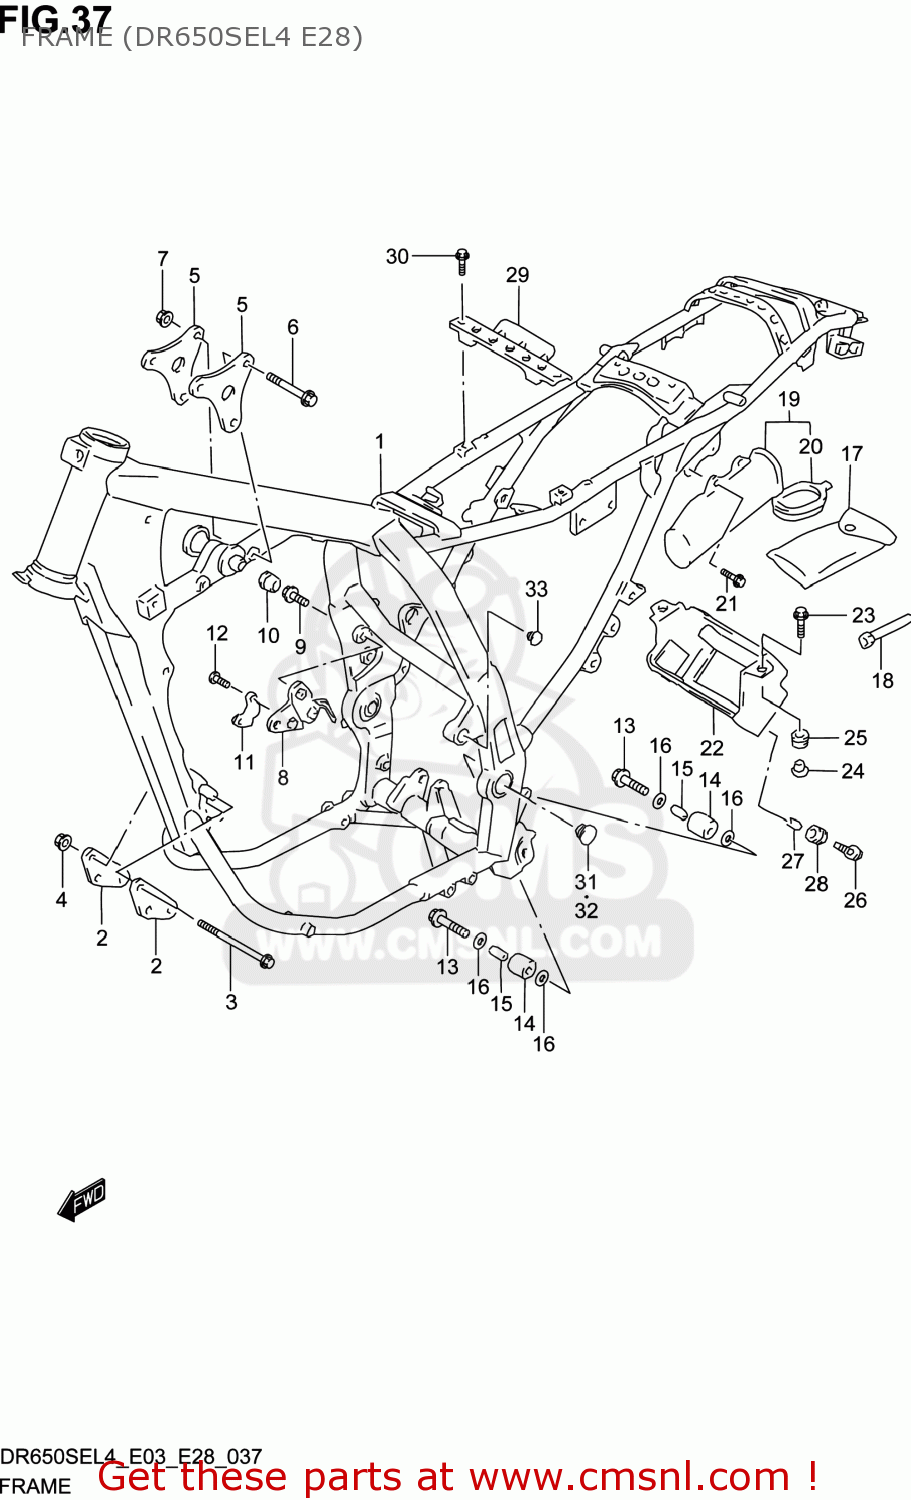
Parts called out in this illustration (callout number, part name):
1	FRAME(GLAY)
2	PLATE,ENG MTG FR
3	BOLT(8X100)
4	NUT
5	PLATE,ENG MTG UPR
6	BOLT(8X55)
7	NUT
8	PLATE,ENG MTG RR,R
9	BOLT
10	PLUG(OD:22)
11	BRACKET,STOP SWITCH
12	SCREW
13	BOLT(8X38)
14	ROLLER,CHAIN CONTROL UPR
15	SPACER(8.6X12X25.5)
16	WASHER
17	TOOL ASSY
18	SPARK PLUG WRENCH(16)
19	HOLDER,TOOL
20	CAP,HOLDER
21	BOLT(6X16)
22	HOLDER,BATTERY
23	BOLT(6X20)
24	WASHER
25	CUSHION
26	BOLT(6X16)
27	SPACER(6.1X9X7.5)
28	CUSHION
29	PLATE,BATTERY FITING
30	BOLT
31	PLUG,FRAME PIVOR,R
32	PLUG,FRAME PIVOR,L
33	PLUG,FRAME BOSS
